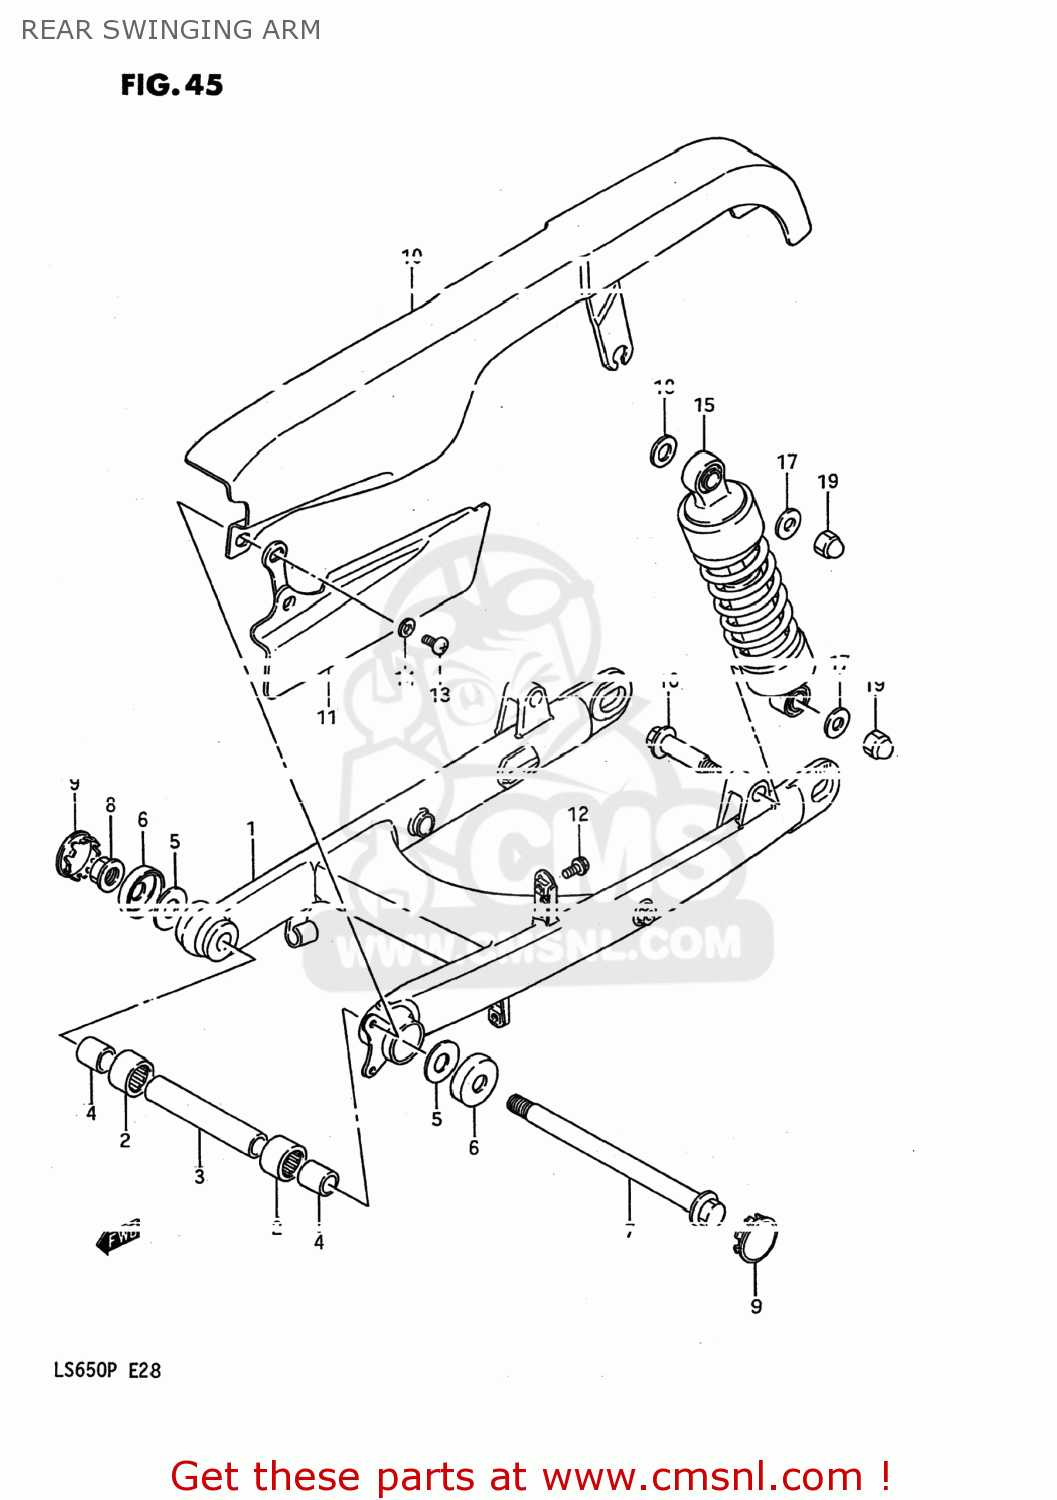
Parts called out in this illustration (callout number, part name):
1	SWING ARM,REAR
2	BEARING(22X29X30)
3	SPACER,RR SWGARM PIVOT CTR
4	SPACER,RR SWGARM PIVOT
5	WASHER
6	CVR,RR SWGARM DUST SEAL(OD:40)
7	SHAFT,RR SWINGINGARM PIVOT
8	NUT
9	CAP,RR SWINGING ARM PIVOT,R
10	BELT CASE,UPR
11	BELT CASE,LWR
12	BOLT
13	SCREW
14	WASHER,LOCK
15	ABSORBER ASSY,RR SHOCK
16	BOLT,RR SHOCK ABSORBER LWR
17	WASHER
18	WASHER(14.5X29X2.3)
19	NUT
